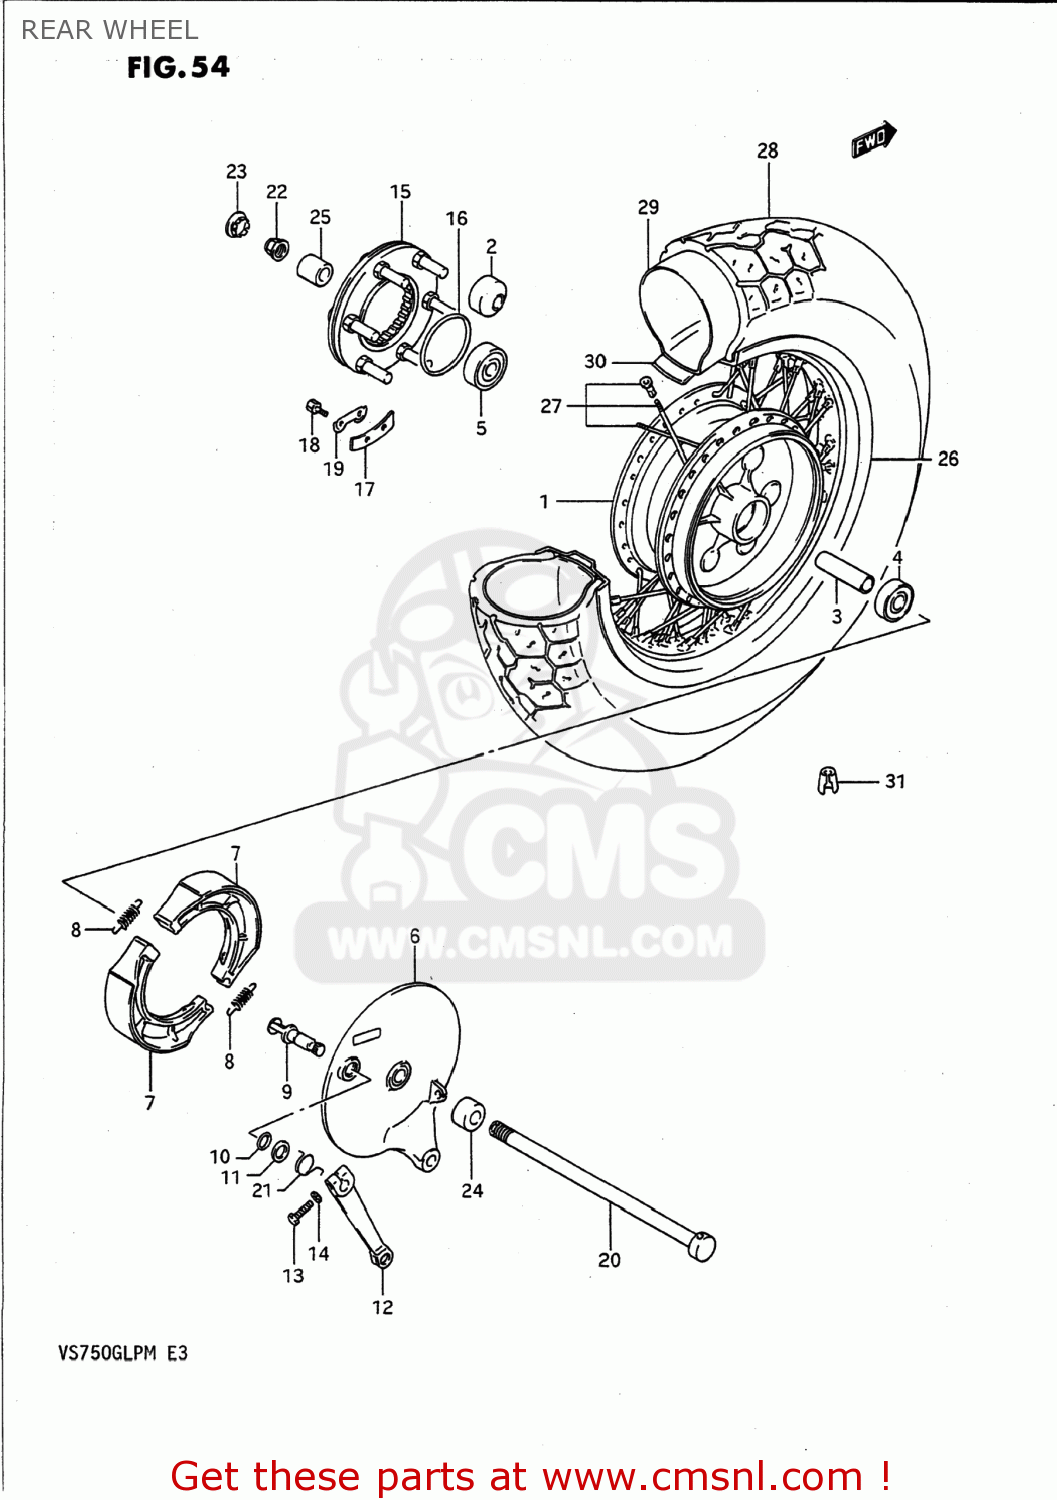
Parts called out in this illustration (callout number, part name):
1	HUB SET,REAR
2	BUSH
3	SPACER(17.5X25X80)
4	BEARING
5	BEARING
6	PANEL,REAR BRAKE ANCHOR
7	SHOE,BRAKE
8	SPRING,BRAKE SHOE
9	CAM,RR BRAKE
10	O-RING,BOSS
11	WASHER (15X24X1.6)
12	LEVER,RR BRAKE CAM
13	BOLT
14	WASHER,LOCK
15	JOINT ASSEMBLY,REAR HUB DRUM
16	O RING(D:2.1,ID:65)
17	WASHER,THRUST(T:1.6)
18	BOLT(6X16)
19	WASHER
20	AXLE,REAR
21	SPRING
22	NUT
23	CAP,RR AXLE,R
24	SPACER,REAR AXLE,RIGHT
25	SPACER,RR AXLE,L
26	RIM,REAR WHEEL
27	SPOKE SET,RR WHEEL
28	TIRE
29	TUBE ASSEMBLY,WHEEL,INNER
30	PROTECTOR,WHL INR TUBE
31	BALANCER,WHEEL
